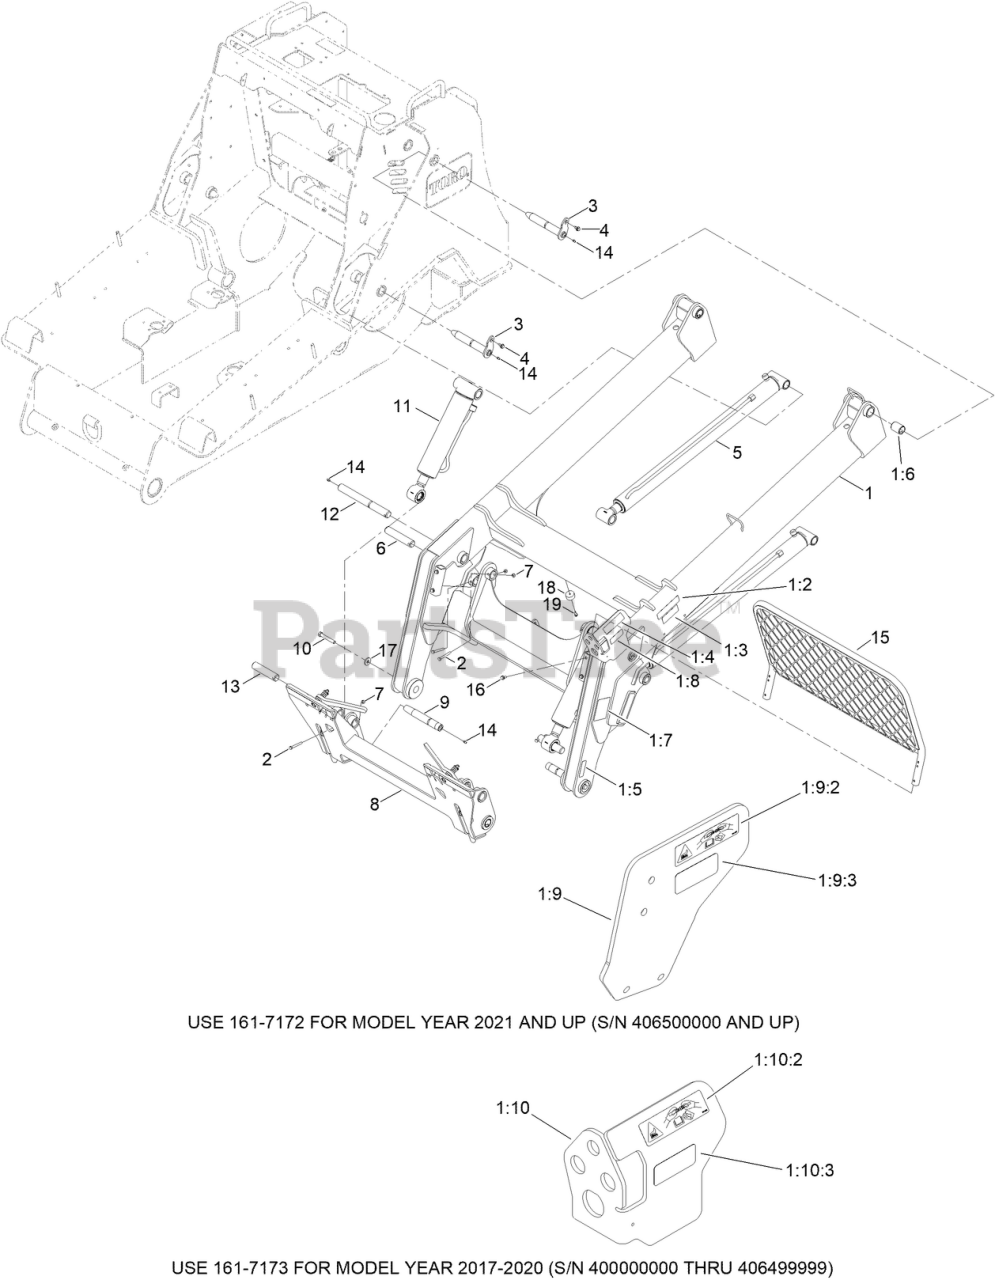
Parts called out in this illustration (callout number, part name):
1	LOADER ARM-STANDARD, ASM
1:2	DECAL-WARNING, CRUSHING
1:3	DECAL-WARNING, BYSTANDERS
1:4	DECAL-CAUTION
1:5	DECAL-WARNING, PINCH POINT
1:6	BUSHING-SPRING
1:7	DECAL-WARNING, BUCKET
1:8	DECAL-WARNING, HYD PRESSURE
1:9	PLATE-MOUNT QC
1:9:2	DECAL-CAUTION
1:9:3	DECAL-WARNING, HYD PRESSURE
1:10	MOUNT-PLATE QD
1:10:2	DECAL-CAUTION
1:10:3	DECAL-WARNING, HYD PRESSURE
2	SCREW-HH
3	PIVOT PIN ASM
4	BOLT-SHOULDER
5	CYL-HYD
6	PIN-LINK
7	NUT-LOCK, NI
8	QTACH ASM
9	PIN-LINK, TAPER
10	SCREW-HH
11	CYL-HYD
12	PIN-LINK
13	PIN-LINK
14	FITTING-GREASE
15	SCREEN-DEBRIS
16	SCREW-HHF
17	WASHER-FLAT
18	BUMPER-RECESSED
19	SCREW-HWH, THREAD ROLL
